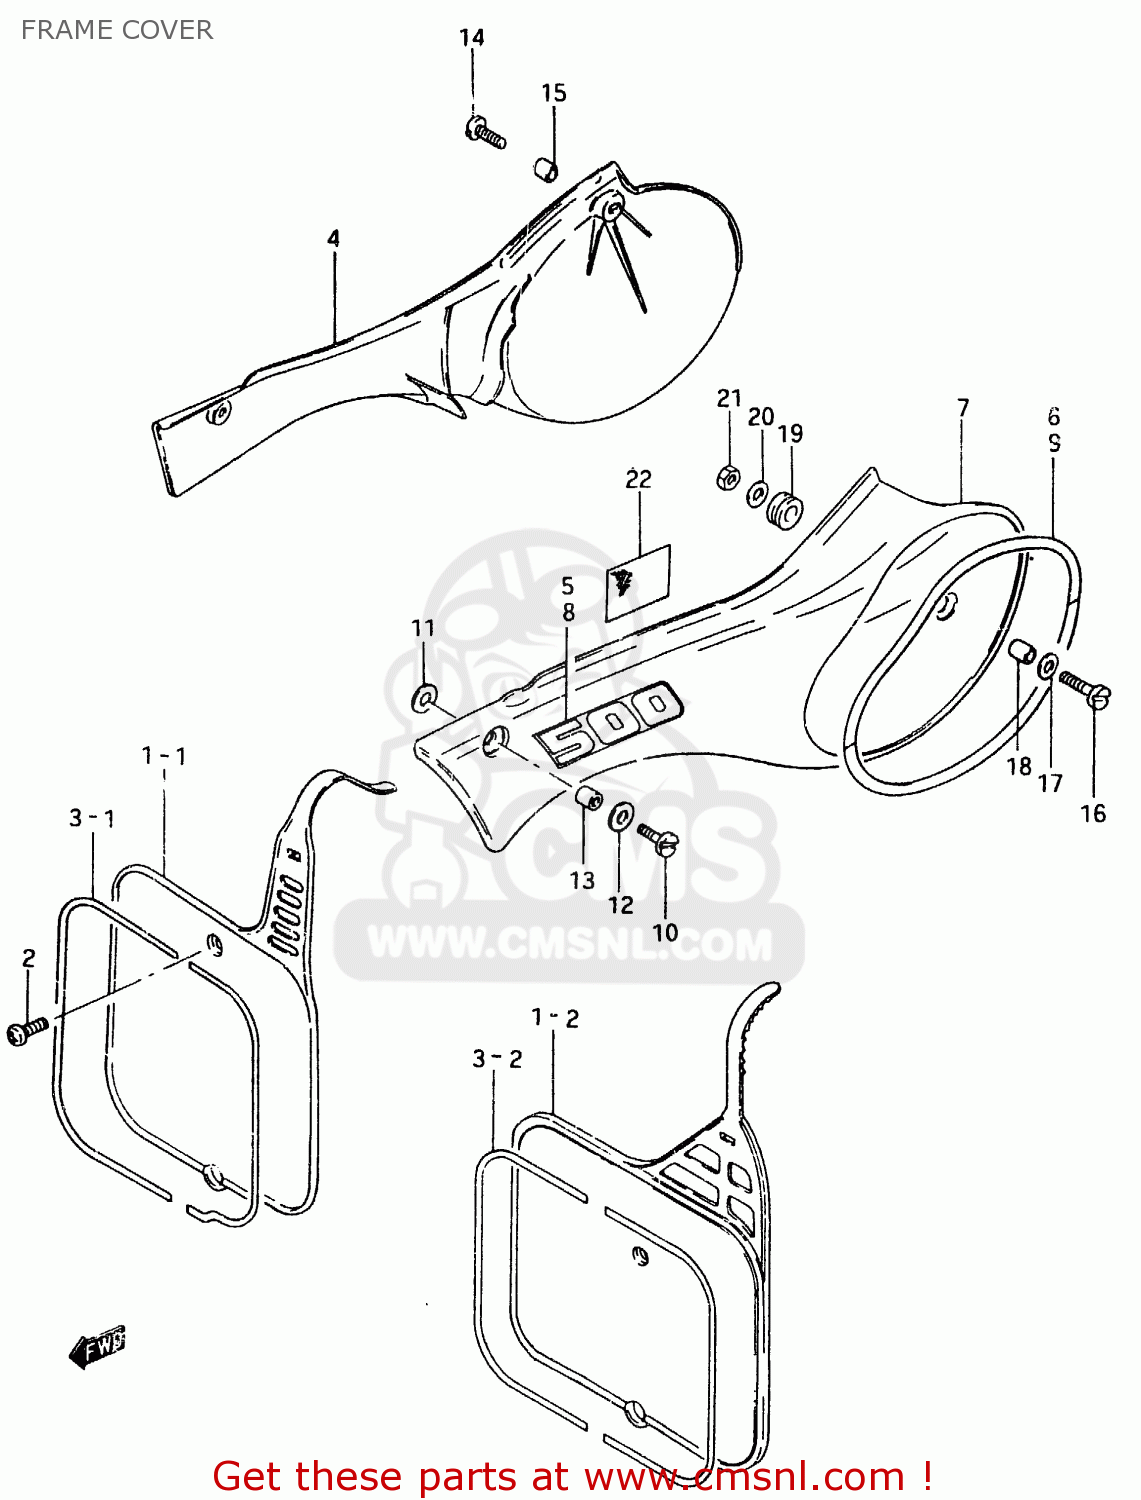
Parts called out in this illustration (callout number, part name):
1	PLATE,NUMBER,FRONT
2	PLATE,NUMBER,FRONT
3	SCREW
4	TAPE,SET
5	TAPE,SET
6	COVER,FRAME,R(YELLOW)
7	EMBLEM
8	TAPE SET,FRAME COVER
9	COVER,FRAME,L(YELLOW)
10	EMBLEM,FRAME COVER
11	TAPE SET,FRAME COVER,RIGHT
12	SCREW(6X14)
13	WASHER, REAR
14	SPACER (6.1X8X3.5)
15	SCREW(6X14)
16	SPACER (6.1X8X3.5)
17	SCREW(6X20)
18	WASHER (6.5X24X1.6)
19	SPACER (6.1X9X9)
20	CUSHION
21	WASHER, REAR
22	NUT 6MM
23	HEAT SHIELD,FRAME COVER
